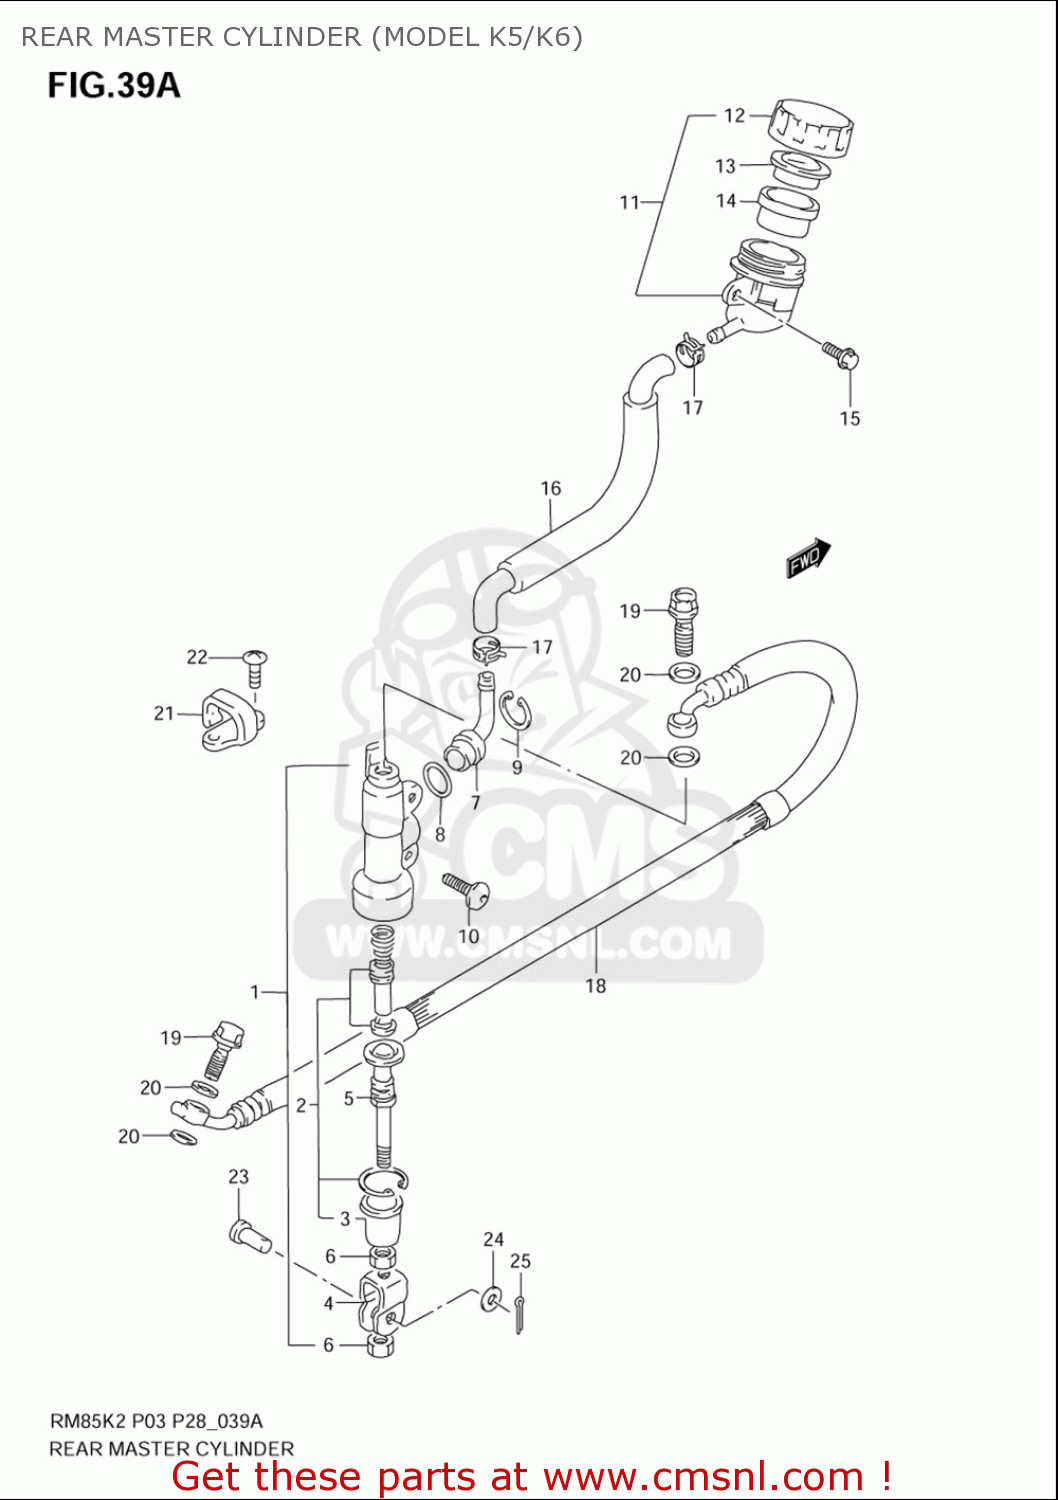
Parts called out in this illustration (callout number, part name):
1	CYLINDER ASSY,RR MASTER
2	PISTON/CUP SET
3	BOOT
4	YOKE
5	ROD,PUSH
6	NUT
7	CONNECTOR
8	O RING
9	CIRCLIP
10	SCREW(6X16)
11	TANK ASSY,RR BRAKE RESERVOIR
12	CAP
13	PLATE
14	DIAPHRAGM
15	BOLT(6X12)
16	HOSE,RESERVOIR TANK
17	CLAMP,RESERVOIR HOSE
18	HOSE,RR BRAKE
19	BOLT UNION
20	WASHER(10X15X1.5)
21	GUIDE,RR BRAKE HOSE
22	SCREW
23	PIN(8X20)
24	WASHER (8.5X14X1.6)
25	PIN
